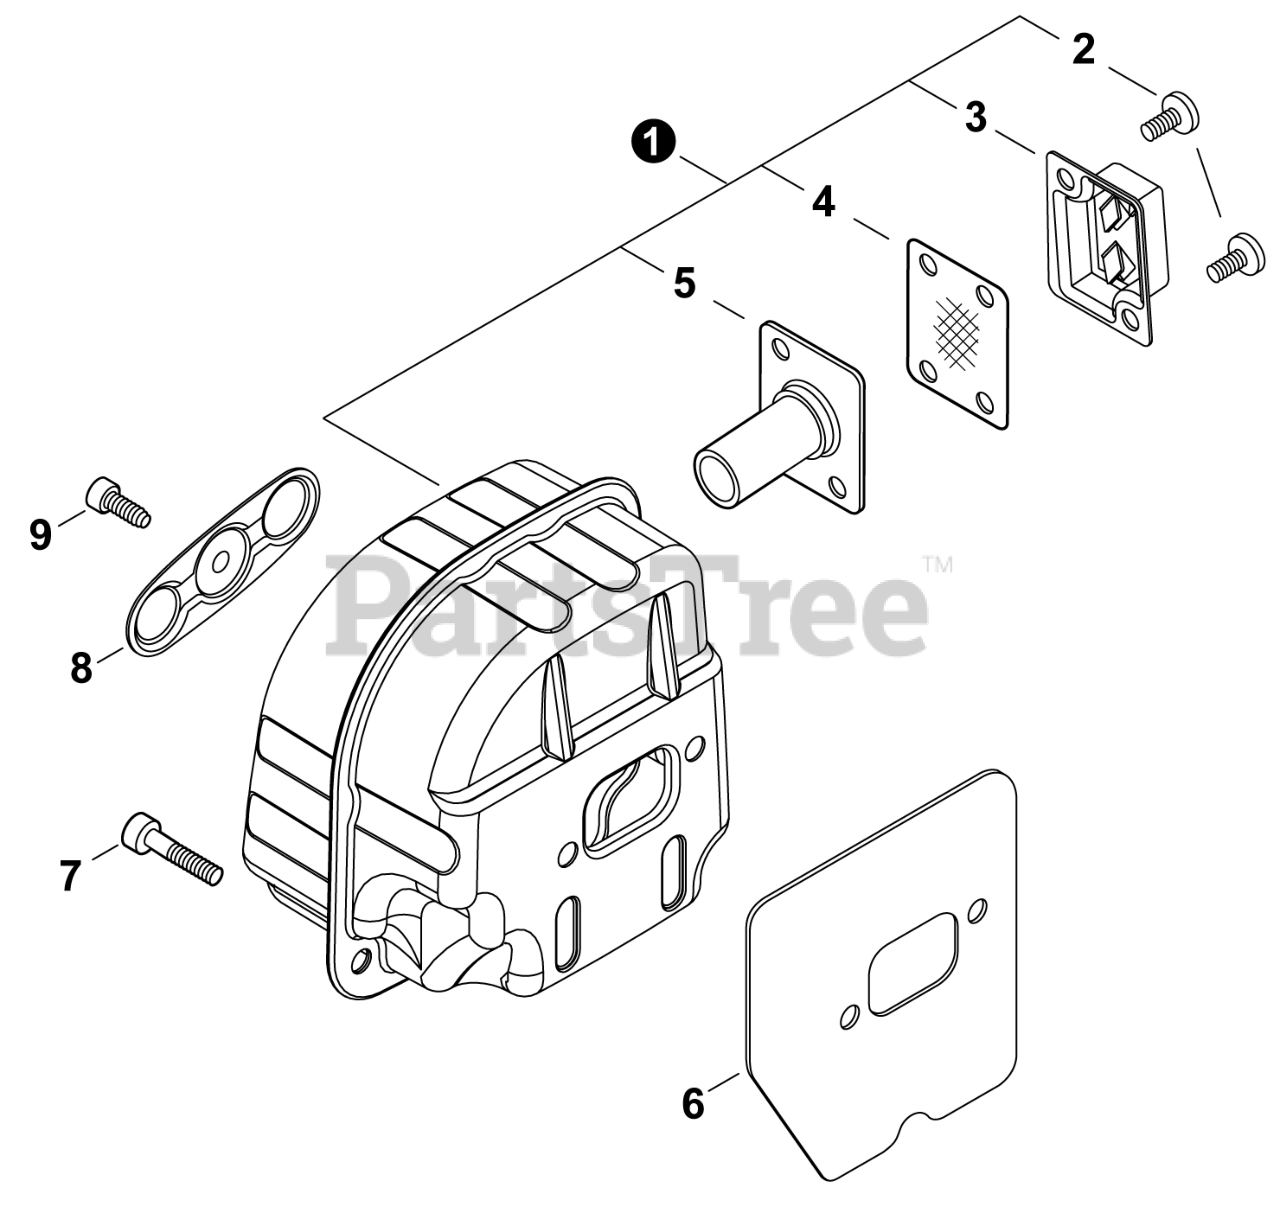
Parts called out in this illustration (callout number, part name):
1	MUFFLER ASSY
2	SCREW M4x6
3	OUTLET, EXHAUST
4	SCREEN, SPARK ARRESTER
5	GUIDE, EXHAUST
6	GASKET, EXHAUST
7	BOLT M5x18
8	PLATE, MUFFLER
9	BOLT 4x6
